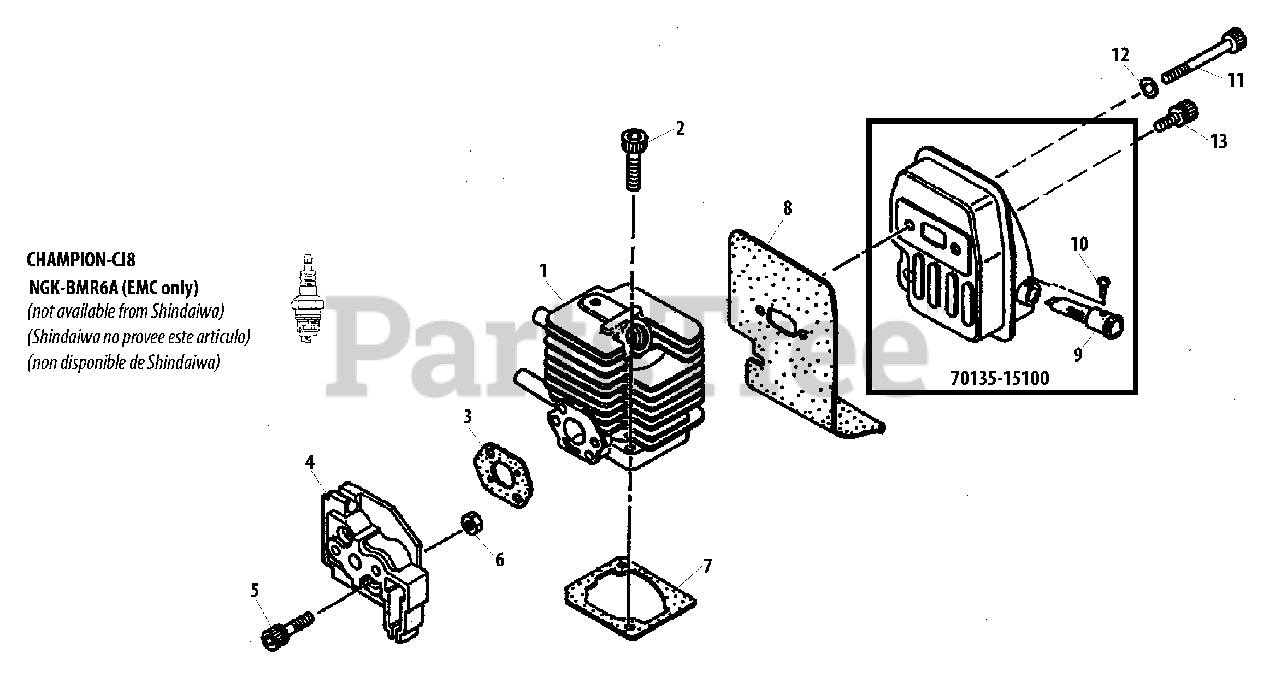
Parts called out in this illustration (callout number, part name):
1	CYLINDER
2	BOLT 5×25
3	GASKET, INTAKE
4	INSULATOR
5	BOLT SS M5×30
6	NUT M5×6.3
7	GASKET, CYLINDER
8	GASKET, EXHAUST
9	SCREEN, SPARK ARRESTER
10	SCREW, TAPPING 3×6
11	BOLT M5×50
12	WASHER, FLAT 5.5×10×0.8
13	BOLT 5×12
70135-15100	MUFFLER ASSY
